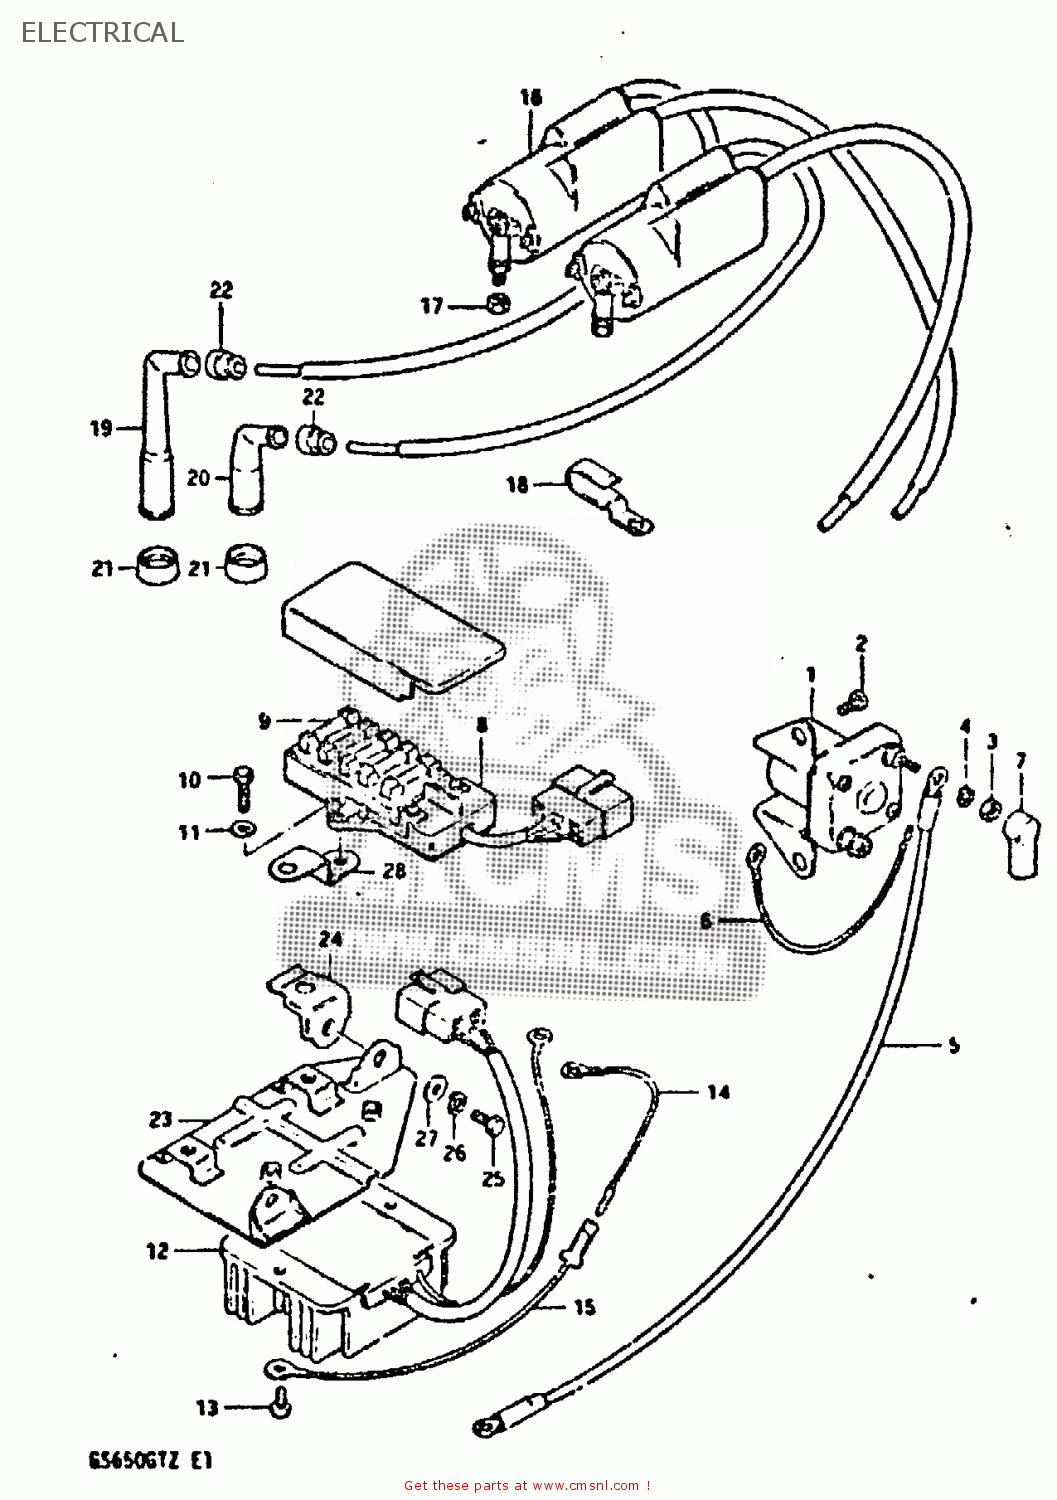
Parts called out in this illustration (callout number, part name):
1	RELAY ASSY,STARTING MOTOR
2	SCREW
3	NUT 6MM
4	LOCK WASHER
5	WIRE,STARTER MOTOR LEAD
6	LEAD WIRE
7	CAP,STARTER RELAY
8	BOX ASSEMBLY,FUSE
9	FUSE(15A)
10	BOLT, UPPER
11	WASHER
12	RECTIFIER ASSEMBLY
13	SCREW 6X12
14	LEAD WIRE
15	WIRE
16	COIL ASSEMBLY,IGNITION
17	NUT
18	CLAMP
19	CAP ASSY,SPARK PLUG
20	CAP,SPARK PLUG
21	SEAL,SPARK PLUG
22	SEAL,SPARK PLU
23	PLATE,ELECTRIC PARTS H
24	BRACKET, PARTS HOLDER
25	BOLT
26	LOCK WASHER
27	WASHER
28	BRACKET
